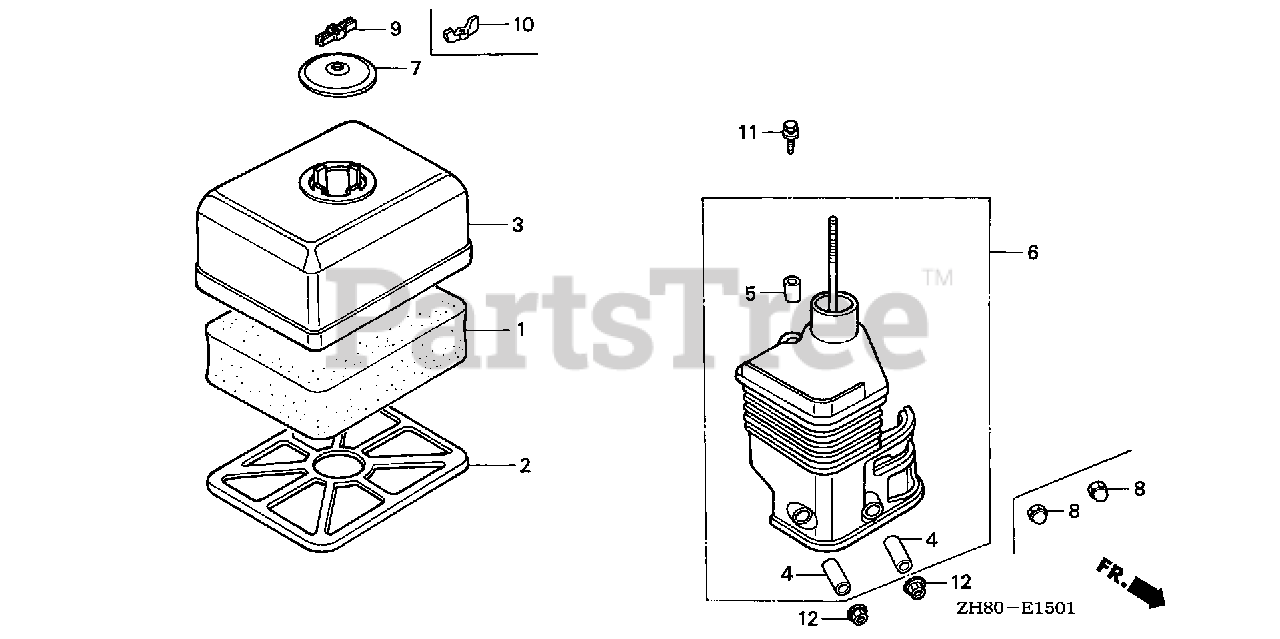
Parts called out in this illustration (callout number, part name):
1	ELEMENT, AIR CLEANER (SEMI-DRY)
2	GRID, AIR CLEANER (SEMI-DRY)
3	COVER, AIR CLEANER (SEMI-DRY)
4	COLLAR, AIR CLEANER
5	COLLAR B, AIR CLEANER
6	ELBOW, AIR CLEANER
7	CAP, CLEANER
10	NUT, TOOL BOX SETTING
11	BOLT, FLANGE (6X20)
12	NUT, FLANGE (6MM)
